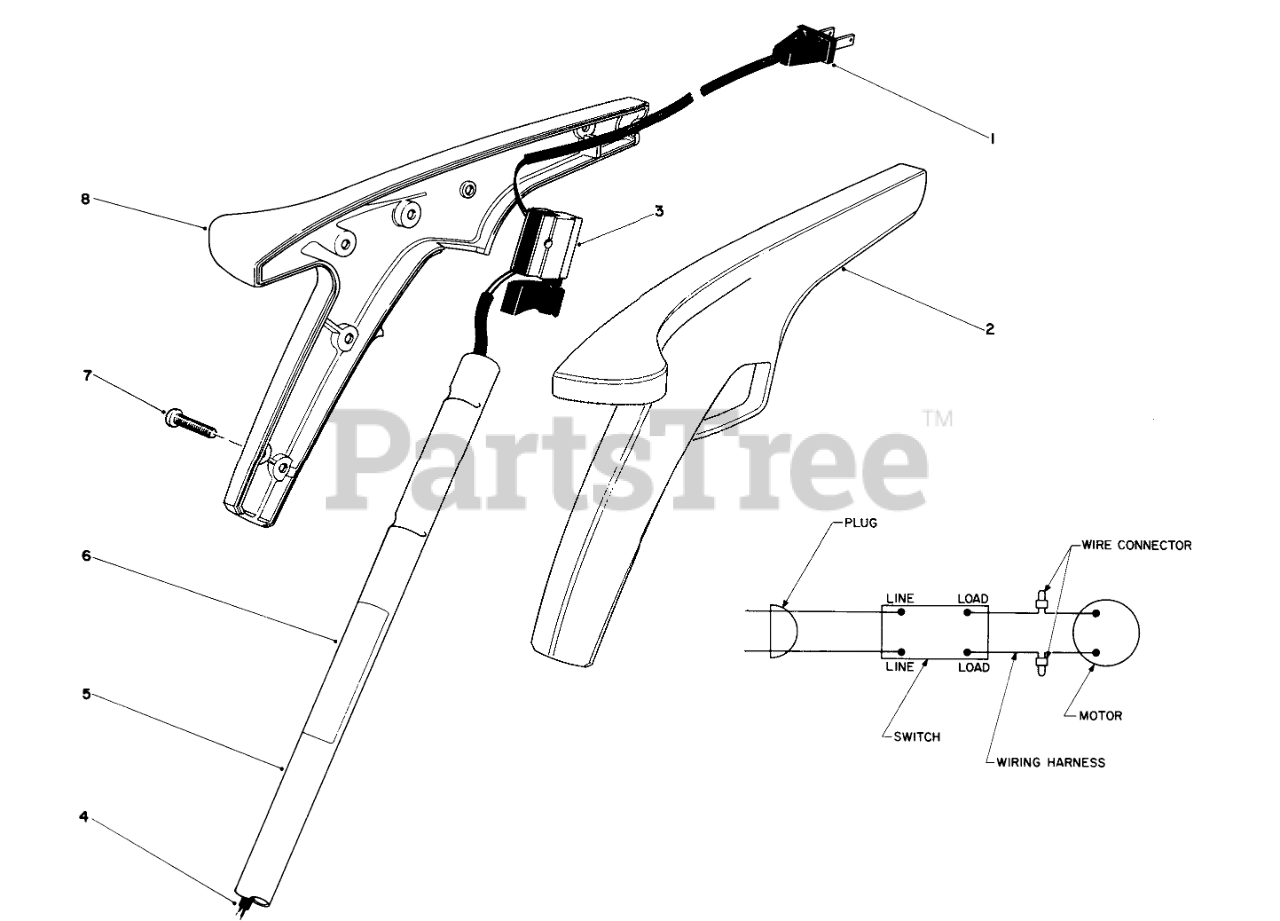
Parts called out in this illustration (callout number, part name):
1	Power Cord
2	L.H. GRIP
3	SWITCH SINGLE SPEED
4	WIRING HARNESS
6	REP. SERIAL PLT
7	#8 X .625" PHILPS PAN H
8	Grip-Right Hand
